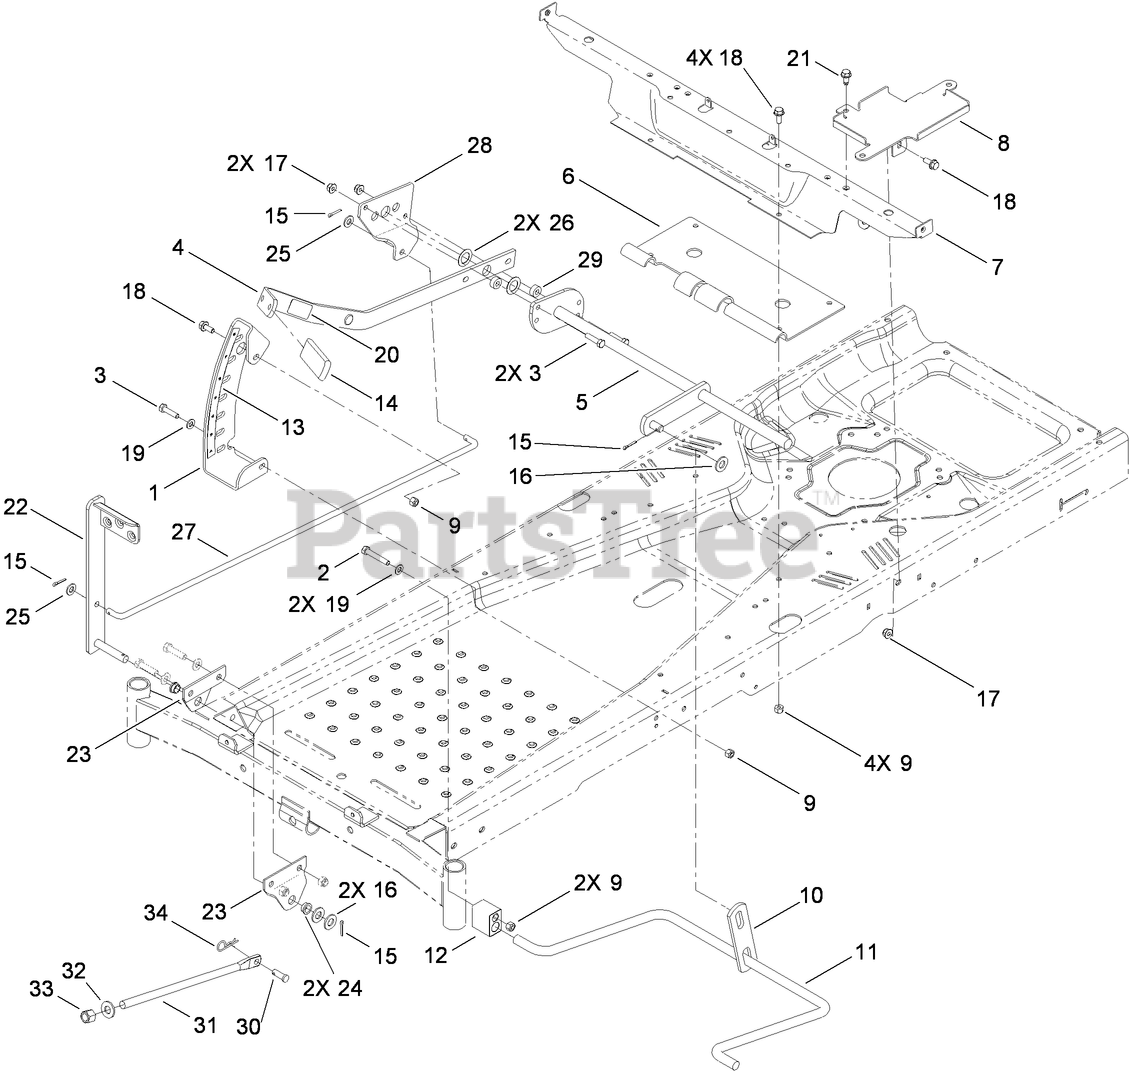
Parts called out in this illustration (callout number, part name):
1	SECTOR-HOC
2	SCREW-HH
3	SCREW-HH
4	LIFT ARM ASM
5	LIFT LEVER ASM
6	PLATE-LIFT
7	BRACKET-SEAT/PODS
8	TRAY-BATTERY
9	NUT-LOCK, NI
10	LINK-LIFT
11	ARM-LIFT, REAR
12	BLOCK-PIVOT
13	DECAL-HOC
14	GRIP-LEVER, LIFT
15	PIN-COTTER
16	WASHER-FLAT
17	NUT-HF, NI
18	SCREW-HHF
19	WASHER-PLAIN
20	DECAL-HOC
21	SCREW-HWH
22	PEDAL ASM
23	BRACKET-FOOTLIFT
24	BUSHING-FLANGE
25	WASHER-FLAT
26	WASHER-THRUST
27	ROD-LIFT
28	PLATE-FOOTLIFT
29	SPACER
30	PIN-CLEVIS
31	ROD-LIFT
32	WASHER-THRUST
33	NUT-LOCK, NI
34	PIN-HAIR
